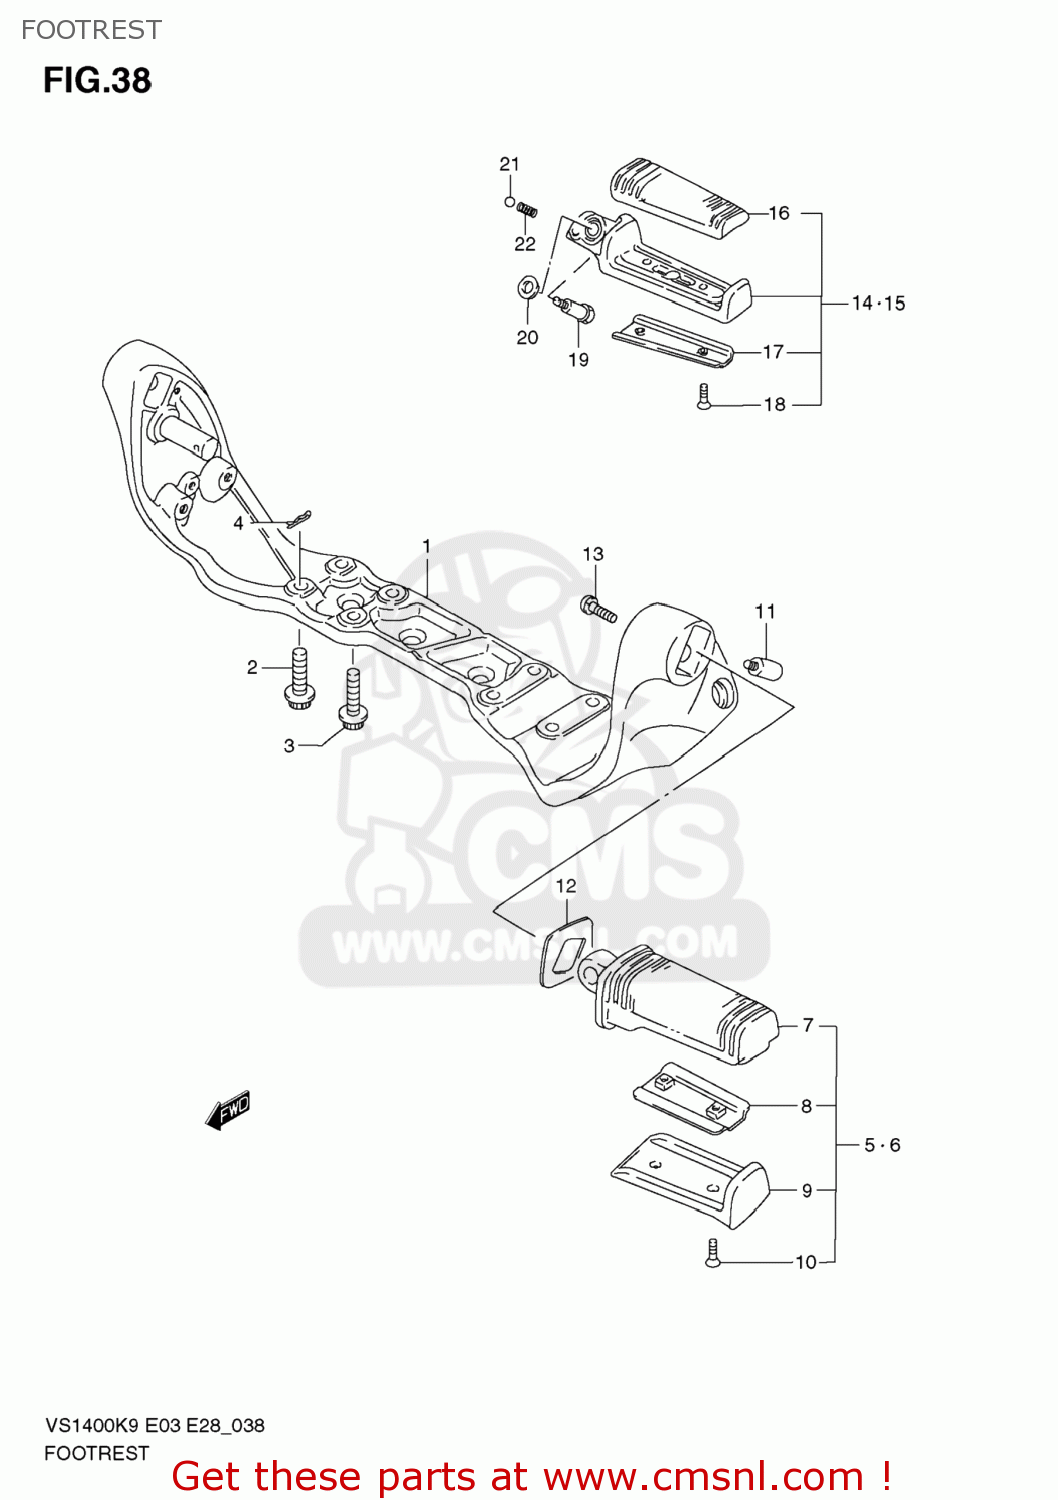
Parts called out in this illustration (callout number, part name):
1	BRACKET,FR FOOTREST
2	BOLT(8X25)
3	BOLT
4	SNAP
5	FOOTREST ASSY,FR,R
6	FOOTREST ASSY,FR,L
7	RUBBER,FR FOOTREST
8	PLATE,RUBBER STOPPER
9	COVER,FR FOOTREST
10	SCREW(5X20)
11	BOLT(6X8)
12	WASHER,FR FOOTREST
13	SCREW
14	FOOTREST ASSY,PILLION,R
15	FOOTREST ASSY,PILLION,L
16	RUBBER,PILLION FOOTREST
17	PLATE,RUBBER STOPPER
18	SCREW(5X16)
19	BOLT(6X34.5)
20	SHIM
21	BALL
22	SPRING
